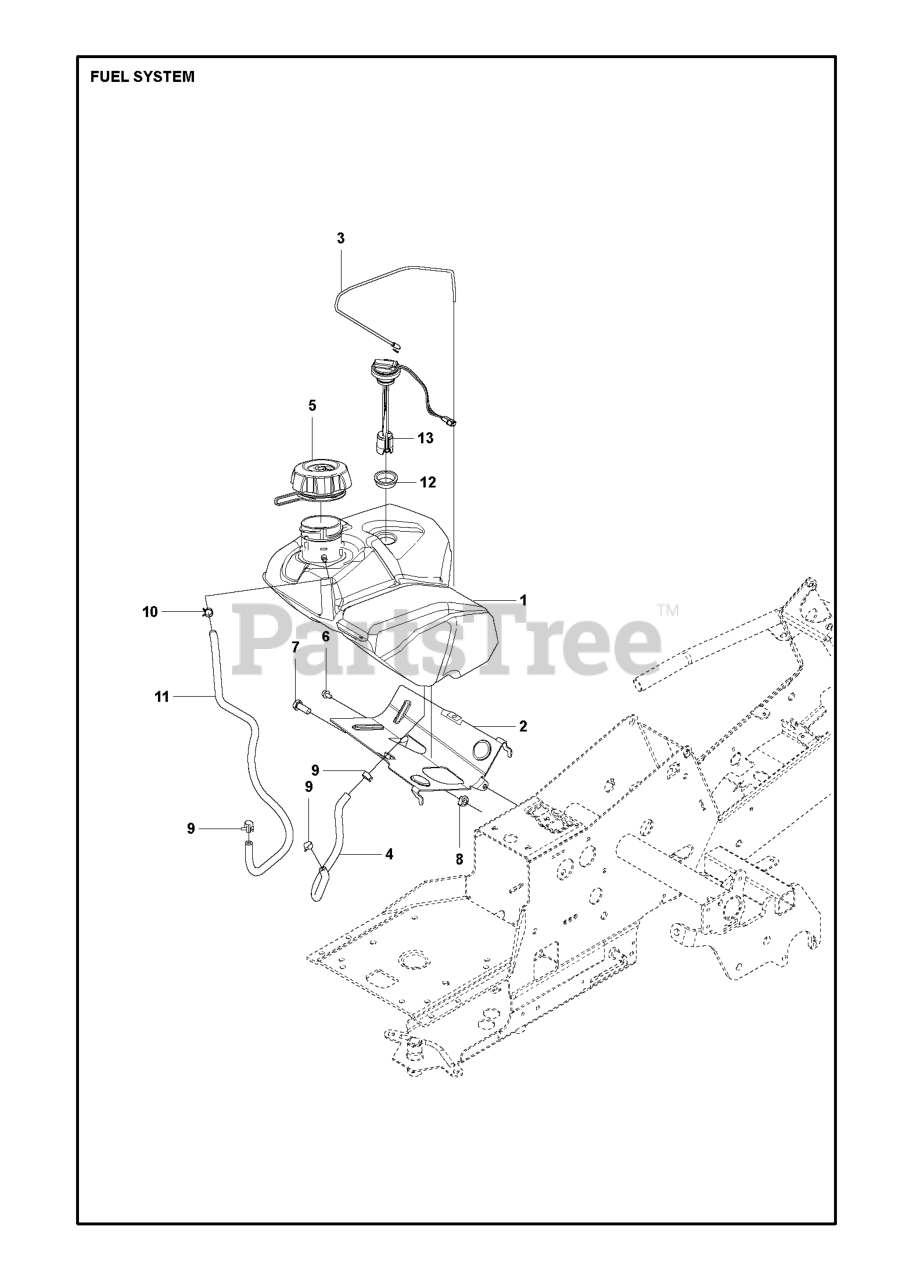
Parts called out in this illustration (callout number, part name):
5	CAP.ASM.FL.RITCH.3"E10.SYM.498
7	Screw M10x25
8	LOCKNUT M6
10	HOSE CLAMP
